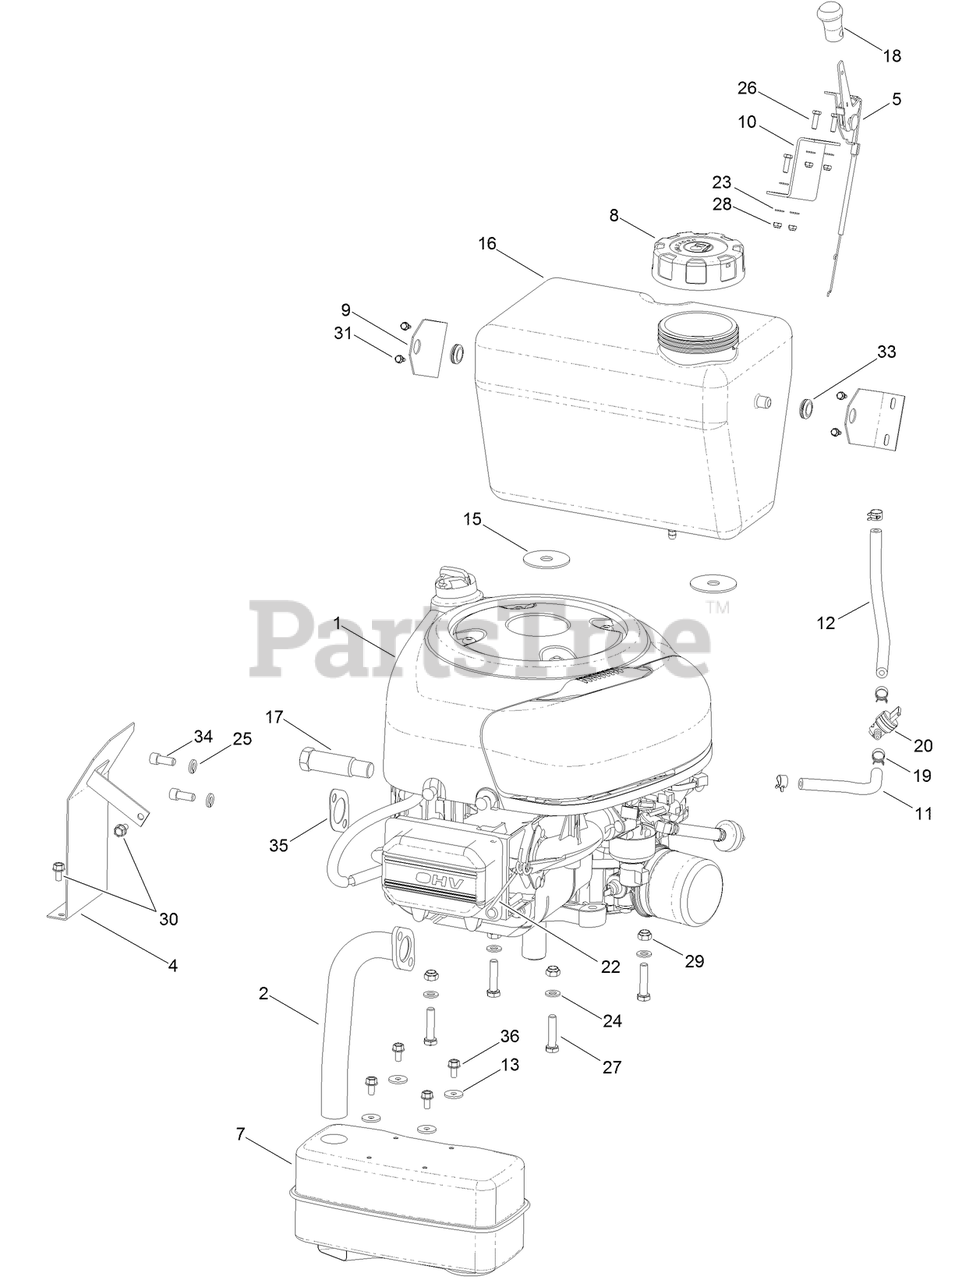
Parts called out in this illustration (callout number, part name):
2	TUBE-EXHAUST
4	COVER-EXHAUST
5	CABLE-THROTTLE/CHOKE
7	MUFFLER
8	CAP-FUEL
9	BRACKET-FUEL, TANK
10	HOLDER
11	LINE-FUEL
12	LINE-FUEL
13	WASHER-FLAT
15	WASHER-RUBBER
16	TANK-FUEL
17	COUPLER-DRAIN, OIL
18	KNOB-THROTTLE/CHOKE
19	CLAMP-LINE, FUEL
20	VALVE-TANK, FUEL
22	HOLDER-HARNESS, WIRING
23	WASHER
24	WASHER-PLAIN
25	WASHER-SPRING
27	SCREW-HH
28	NUT-LOCK
29	NUT-LOCK, NI
30	SCREW-HH
31	SCREW-TAP
33	BUSHING
34	SCREW-HH
35	GASKET
36	SCREW-HHTF
